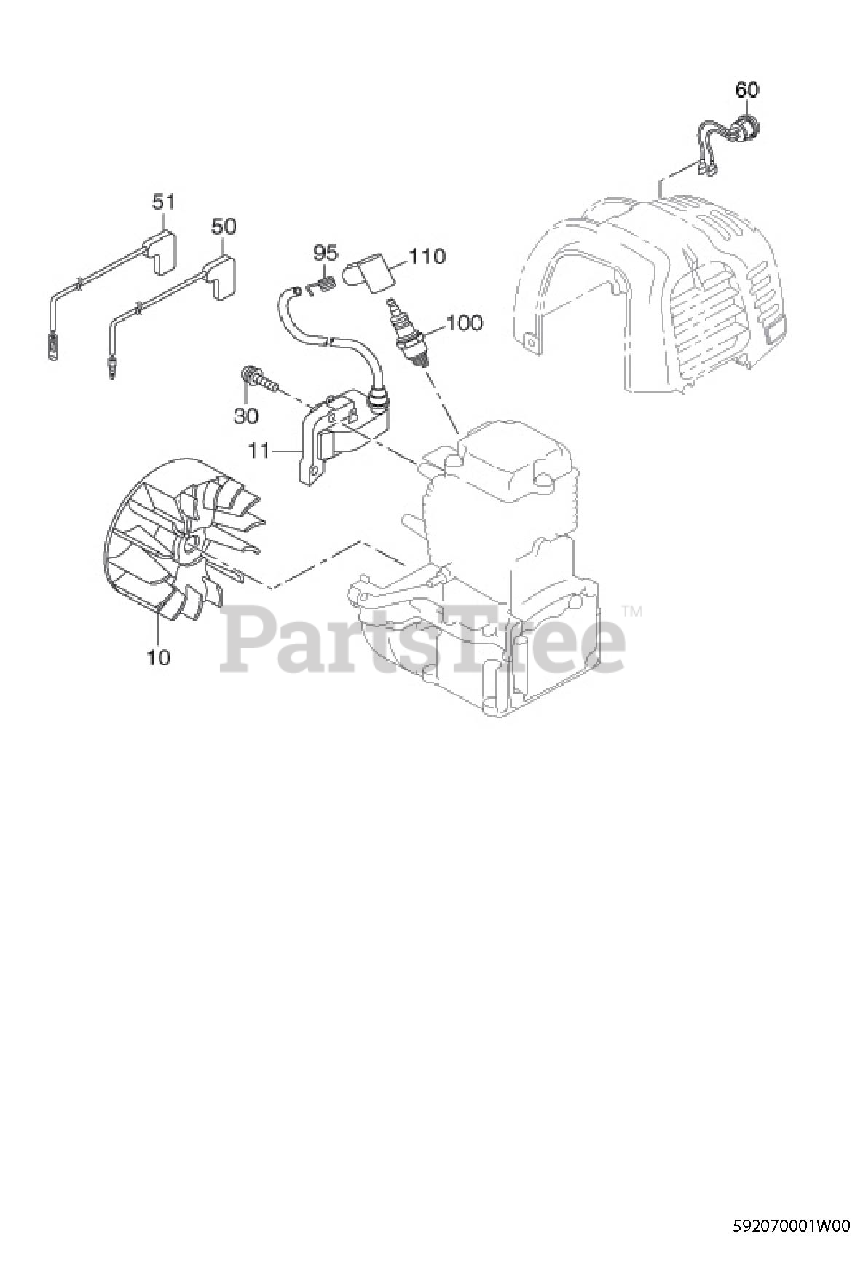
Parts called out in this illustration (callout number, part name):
11	IGNITION COIL
30	SCREW ASSEMBLY
60	STOP SWITCH AY
95	SPRING,PLUG CAP
